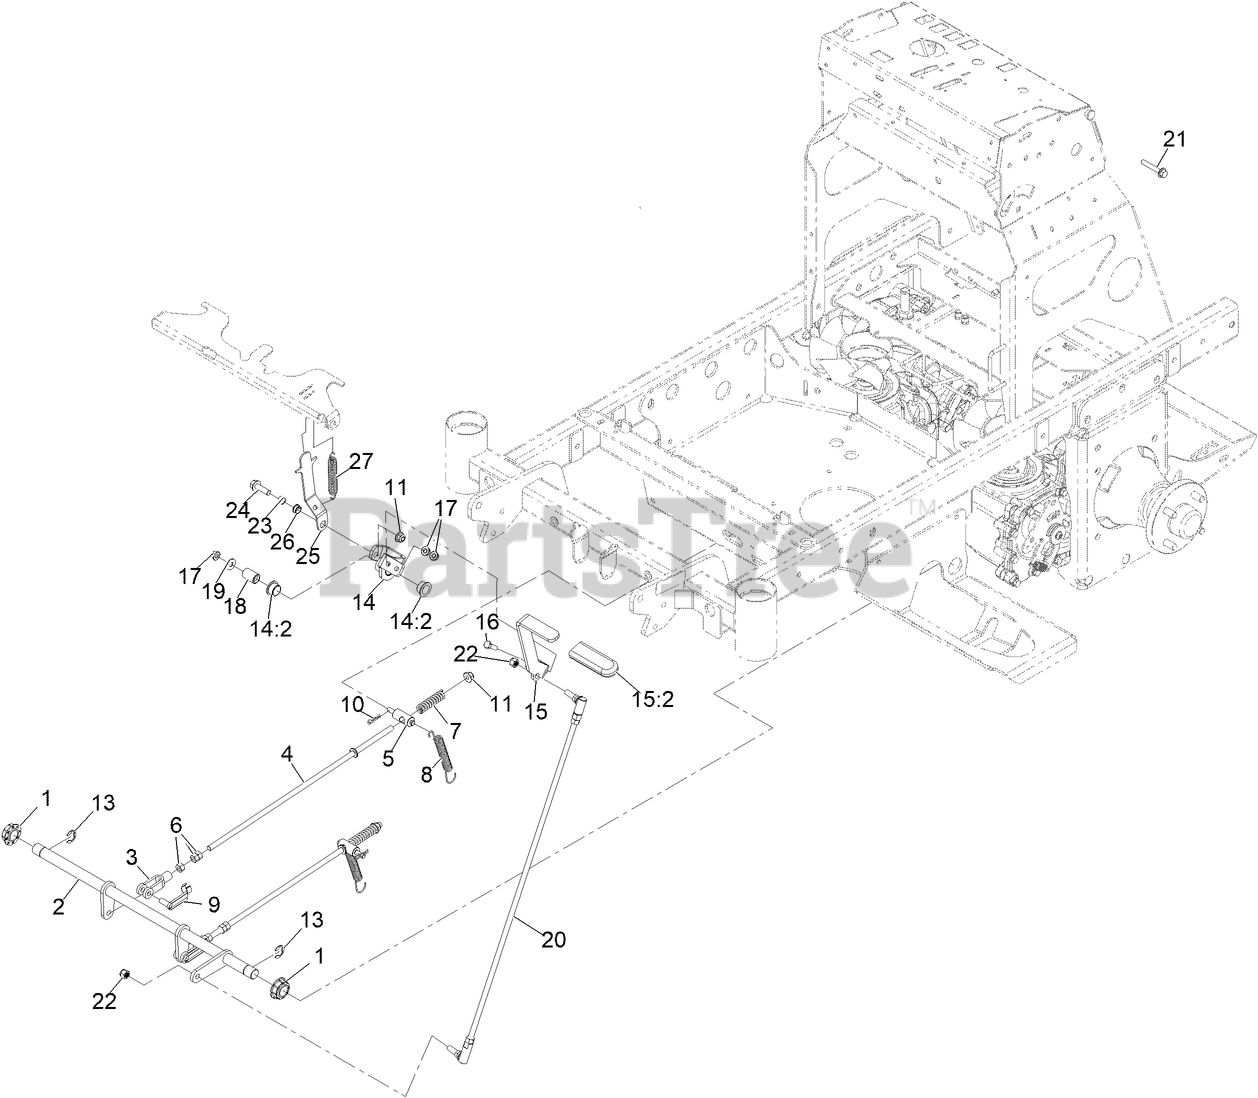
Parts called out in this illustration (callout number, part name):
1	BEARING-SPHERICAL
2	BRAKE ASM
3	YOKE-LINKAGE, BRAKE
4	ROD-BRAKE
5	FITTING-ROD, BRAKE
6	NUT-HEX
7	SPRING-COMPRESSION
8	SPRING-EXTENSION
9	PIN-SPRING, CLEVIS
10	PIN-COTTER
11	Nut-Hex Flange
13	RETAINER, E-RING
14	HANDLE-BRAKE, ASM
14:2	BUSHING-FLANGE
15	ASM-HANDLE, W/ GRIP
15:2	GRIP-LEVER
16	SCREW-HH
17	Nut-Hex Flange
18	SPACER-BRAKE, LINKAGE
19	FLAT WASHER, 5/16 NOM,ST
20	Linkage-Brake
21	SCREW-HHF
22	XREF 126-4803
23	SPACER-BRAKE PIVOT
24	SCREW-HHF
25	LINK-BRAKE CONTROL LOCK
26	BUSHING,SNAP
27	SPRING-EXTENSION
